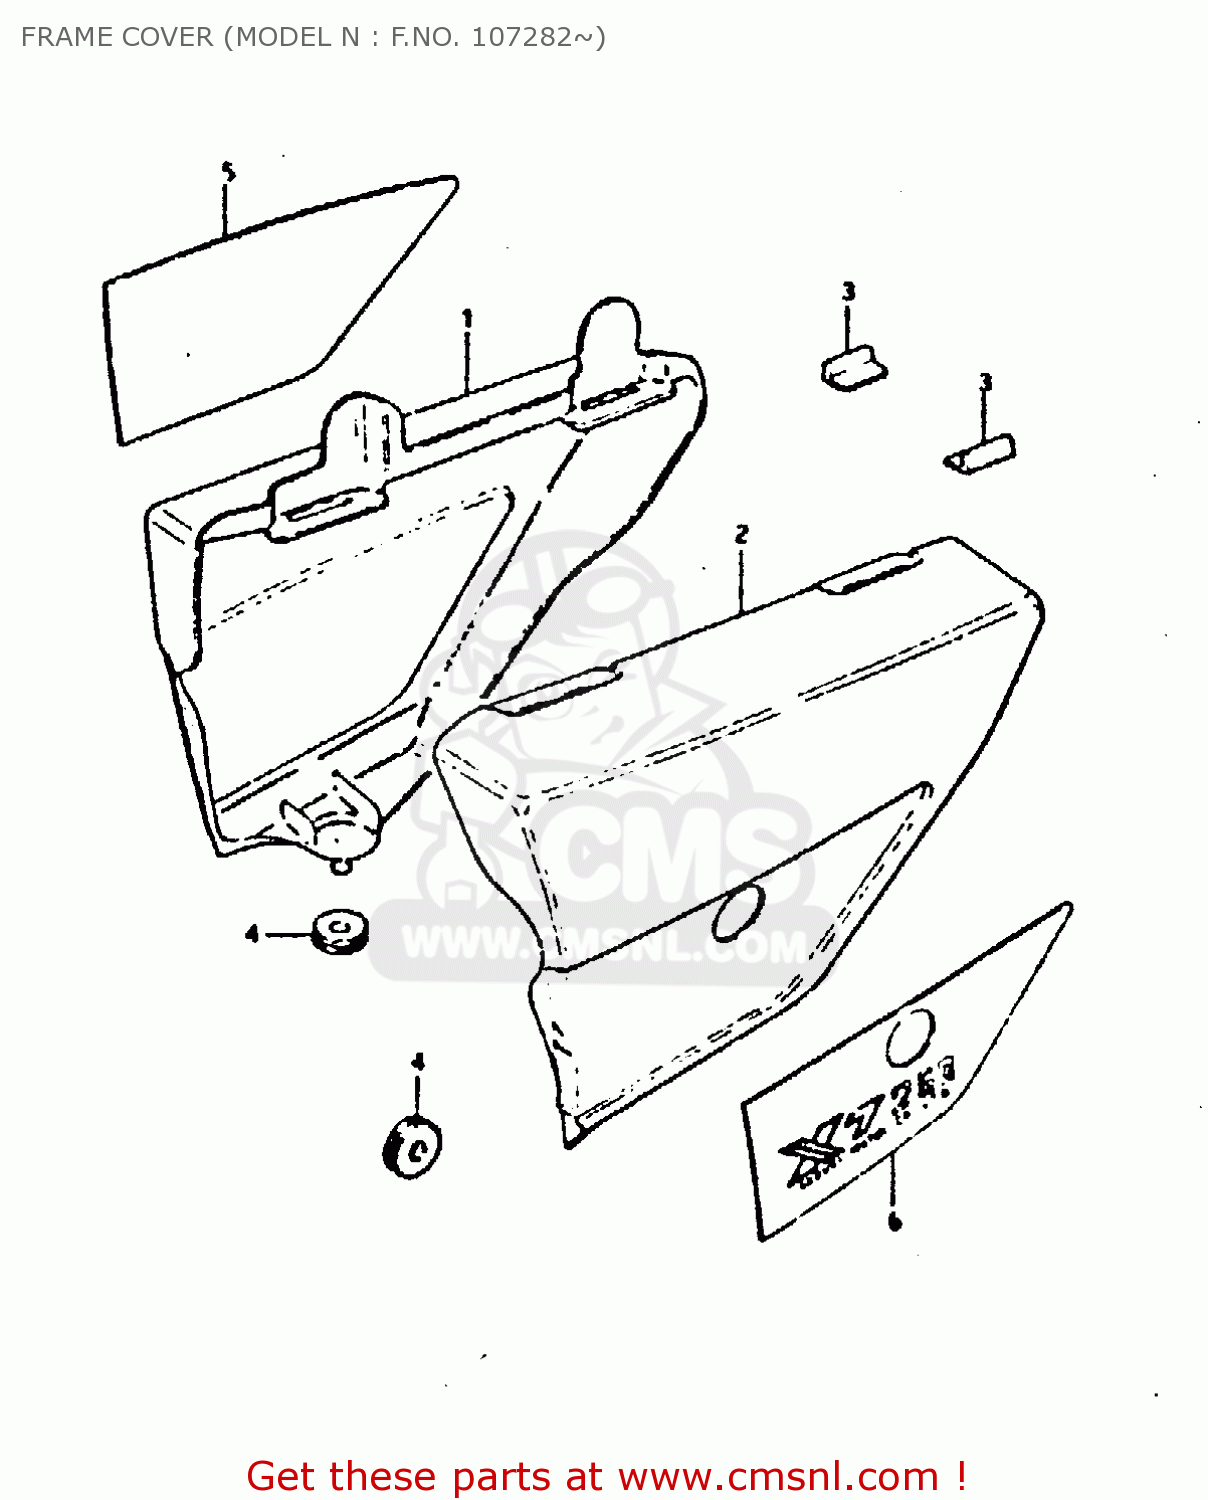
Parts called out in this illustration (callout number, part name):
1	COVER, RH (RED)
2	COVER, LH (RED)
3	CUSHION,FRAME COVER
4	CUSHION
5	EMBLEM, RH
6	EMBLEM, LH
